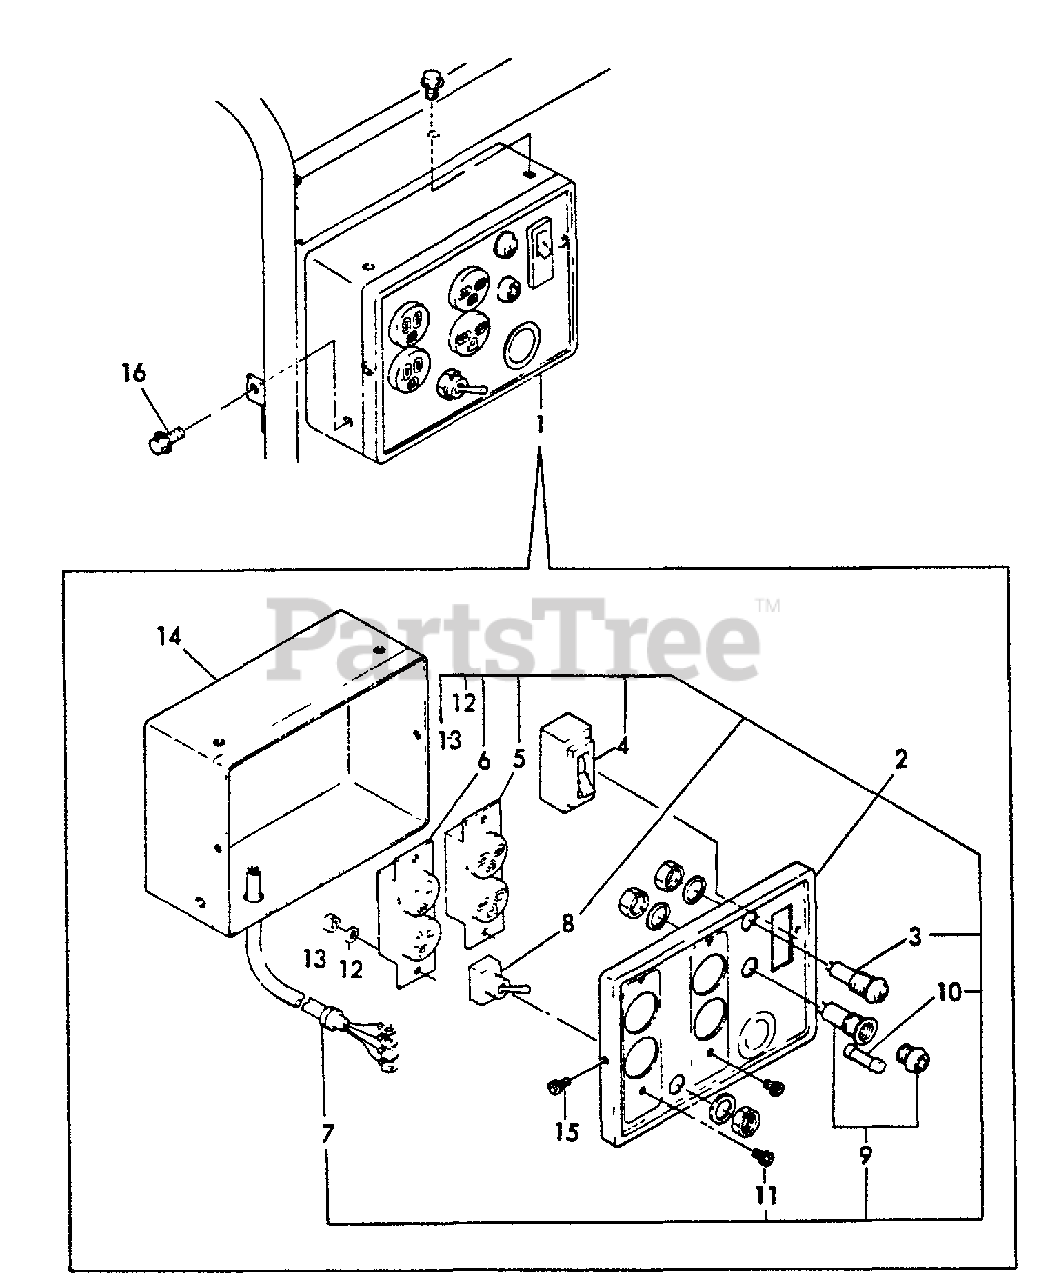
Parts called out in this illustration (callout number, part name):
1	PANEL BOX ASSY
2	PANEL ASSY
3	LAMP, PILOT - 100V
4	BREAKER - 15A
5	AC CONNECT
6	PLUG SOCKET 240V
7	WIRE HARNESS
8	SWITCH
9	HOLDER, FUSE
10	FUSE - 15A
11	SCREW - 4×8
12	WASHER - 4
13	NUT - 4
14	BOX, PANEL
15	SCREW - 4×8
16	BOLT - 6×8 -- PLATED
